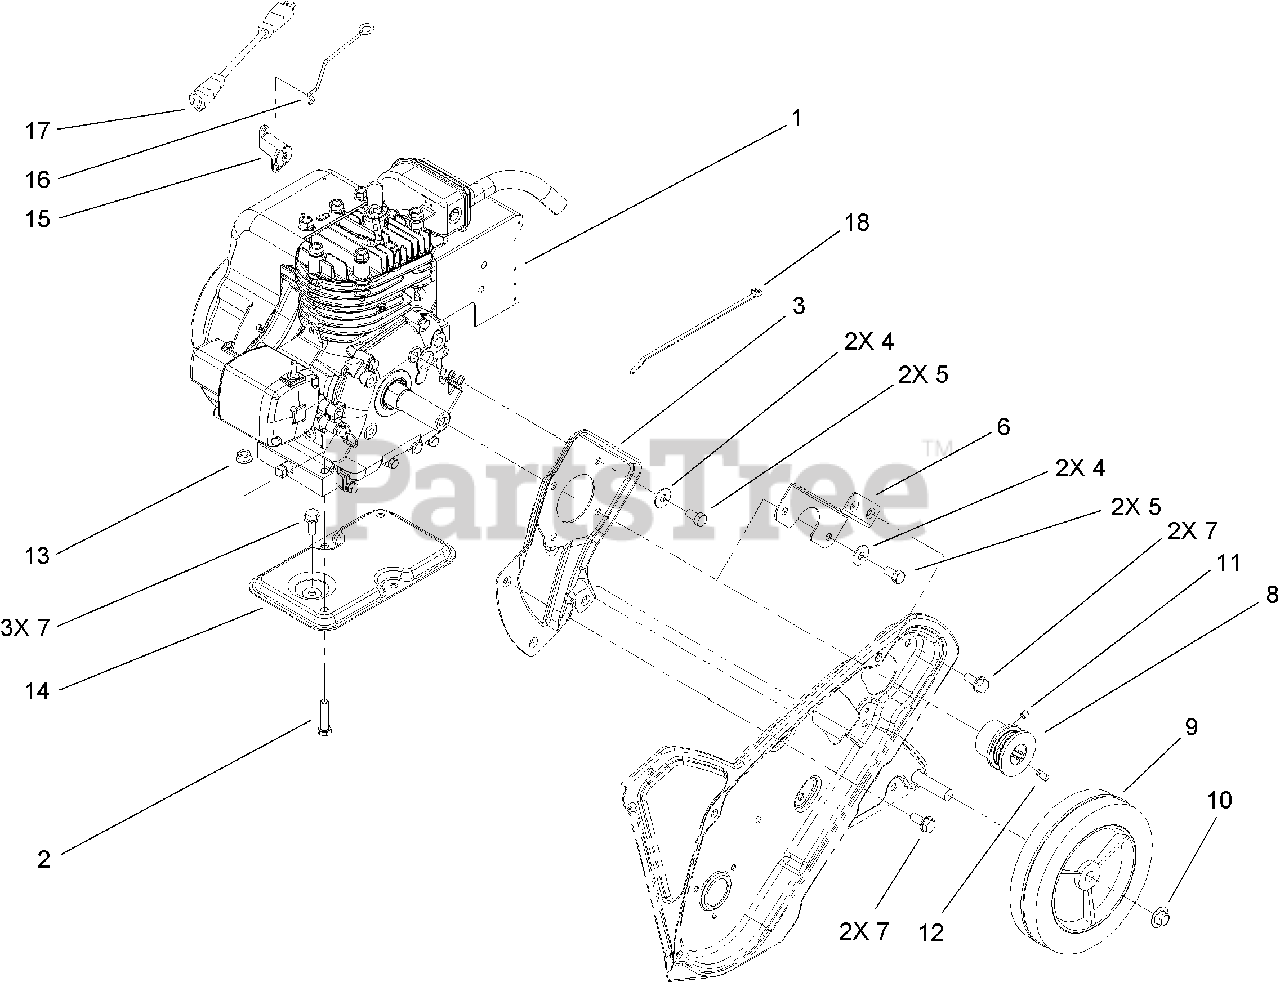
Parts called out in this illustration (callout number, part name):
2	SCREW-HH
3	PLATE-ENGINE, PTO
4	WASHER-BELLEVILLE
5	SCREW-HH
6	SUPPORT-ENGINE, SIDE
7	SCREW-HWHTF
8	PULLEY-ENGINE, 4 CYCLE
11	SCREW-HSH
12	SCREW-SQH
14	SUPPORT-ENGINE
15	BELLCRANK-CHOKE, 4 STROKE
16	LINK-CHOKE KNOB, L-HEAD
17	CORD-EXTENSION
18	STRAP-TIE
